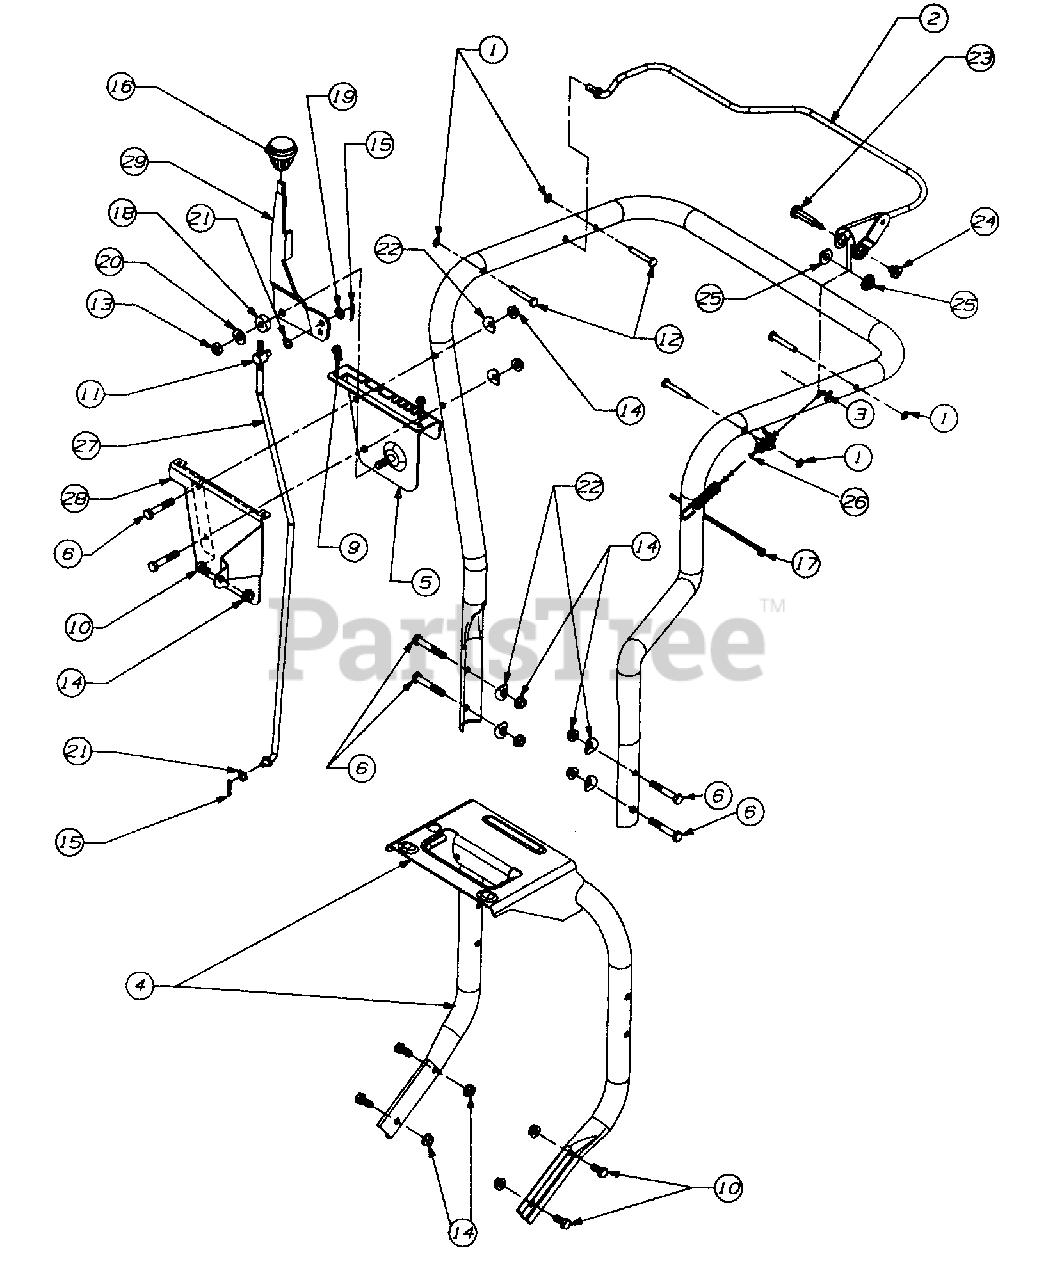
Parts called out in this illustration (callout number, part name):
1	PUSHNUT
9	SCREW-HEX
10	SCREW-HEX
11	FERRULE
12	PIN-STUD
13	NUT-HEX LOCK
14	NUT-HEX LOCK
15	PIN-COTTER
16	KNOB-SHIFT
17	CABLE TIE
18	WASHER-RUBBER
19	WASHER-FLAT
20	WASHER-FLAT
21	WASHER-SPRING
22	WASHER-SADDLE
23	SCREW-SHOULDER
24	NUT-SHOULDER
25	BEARING-FLANGE PLASTIC
26	CABLE-CLUTCH
27	ROD-SHIFT
